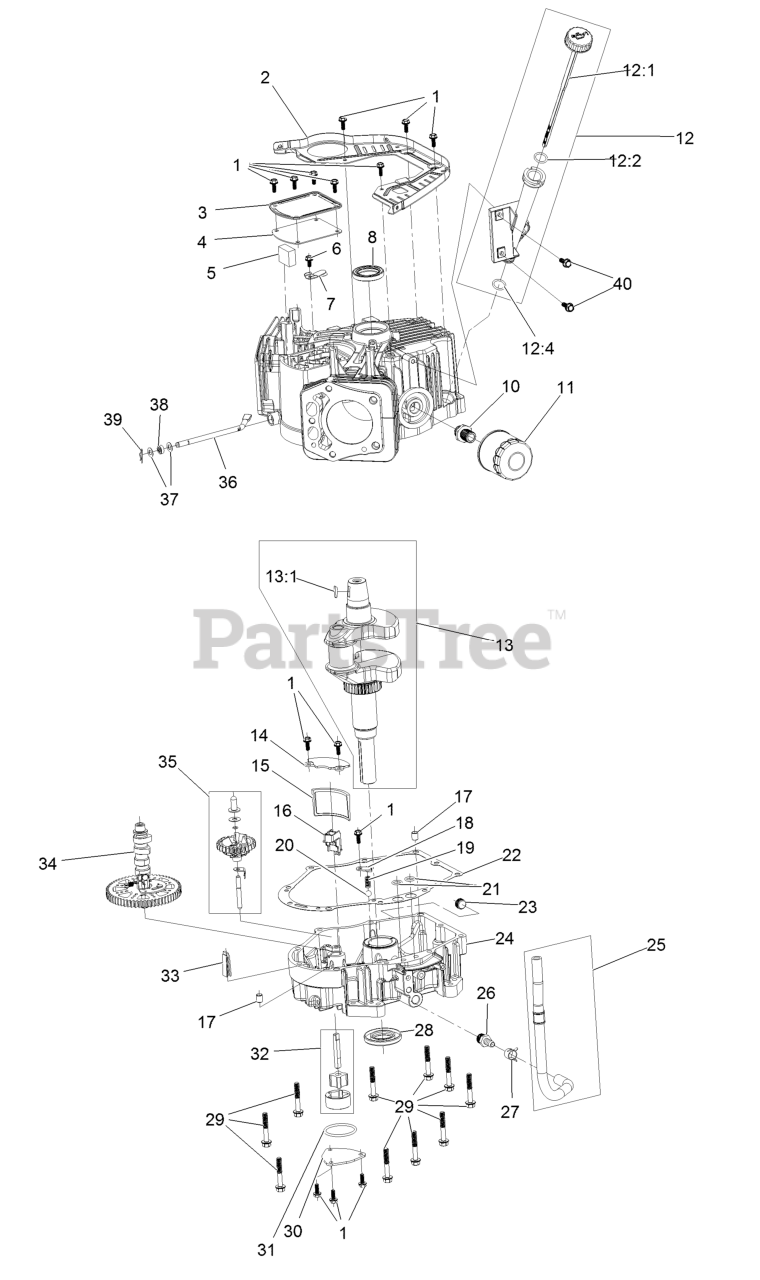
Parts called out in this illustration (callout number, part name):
1	Screw-HHF
3	Cover-Breather
4	Gasket-Breather
5	Filter-Breather
6	Screw-HHF
7	Valve-Breather
8	Seal-Oil
10	Adaptor-Filter, Oil
11	Filter-Oil
12	Oil Tube ASM
12:1	Dipstick
13	Crankshaft
13:1	Key-Woodruff
14	Cover-Screen, Oil
15	Screen-Oil
16	Retainer-Screen
17	Pin-Dowel
18	Plate-Retainer
20	Valve-Ball
22	Gasket-Cover, Crankcase
23	Plug-Drain
24	Cover-Crankcase
25	Oil Drain Hose ASM
26	Fitting-Hose
27	Clamp-Hose
29	Screw-HHF
30	Cover-Oil Pump
32	Oil Pump ASM
33	Deflector-Oil, Rubber
34	Camshaft
35	Governor ASM
36	Rod-Governor
37	Washer-Plain
38	Seal-Oil
39	Pin-Hair
40	Screw-HHF
